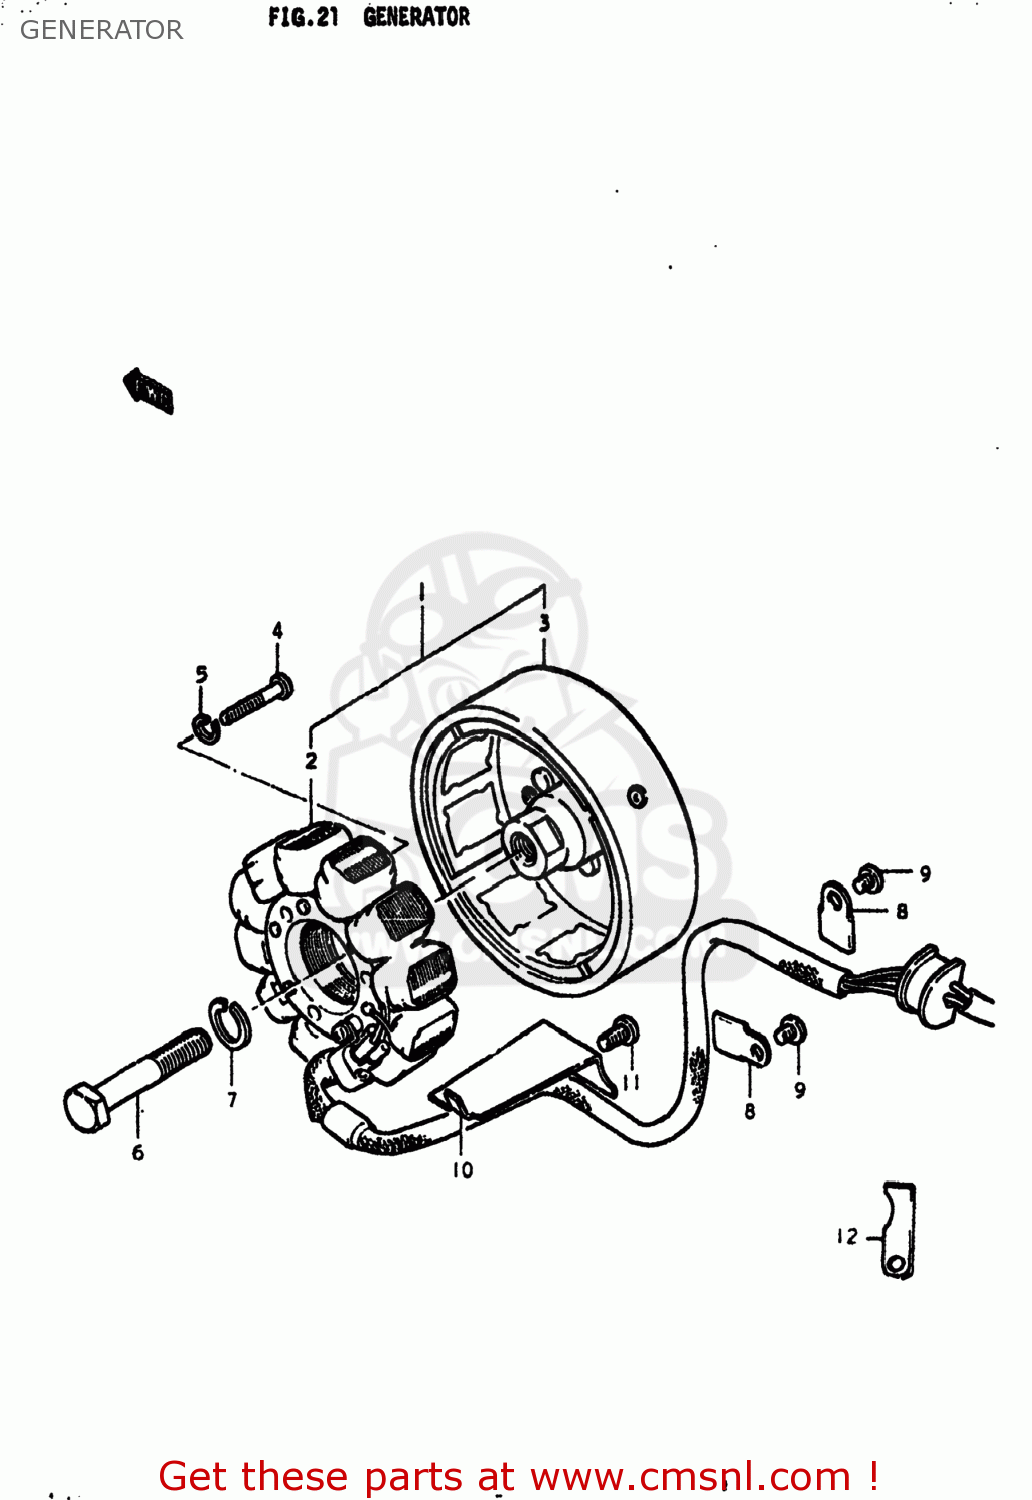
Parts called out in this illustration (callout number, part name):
1	GENERATOR ASSEMBLY
2	STATOR ASSEMBLY
3	ROTOR ASSEMBLY
4	SCREW
5	LOCK WASHER
6	BOLT 12X45
7	WASHER,LOCK 12
8	CLAMP,GENERATOR LEAD WIRE
9	SCREW
10	CLAMP,GENERATOR LEAD WIRE
11	SCREW
12	CLAMP,GENERATOR LEAD WIRE
